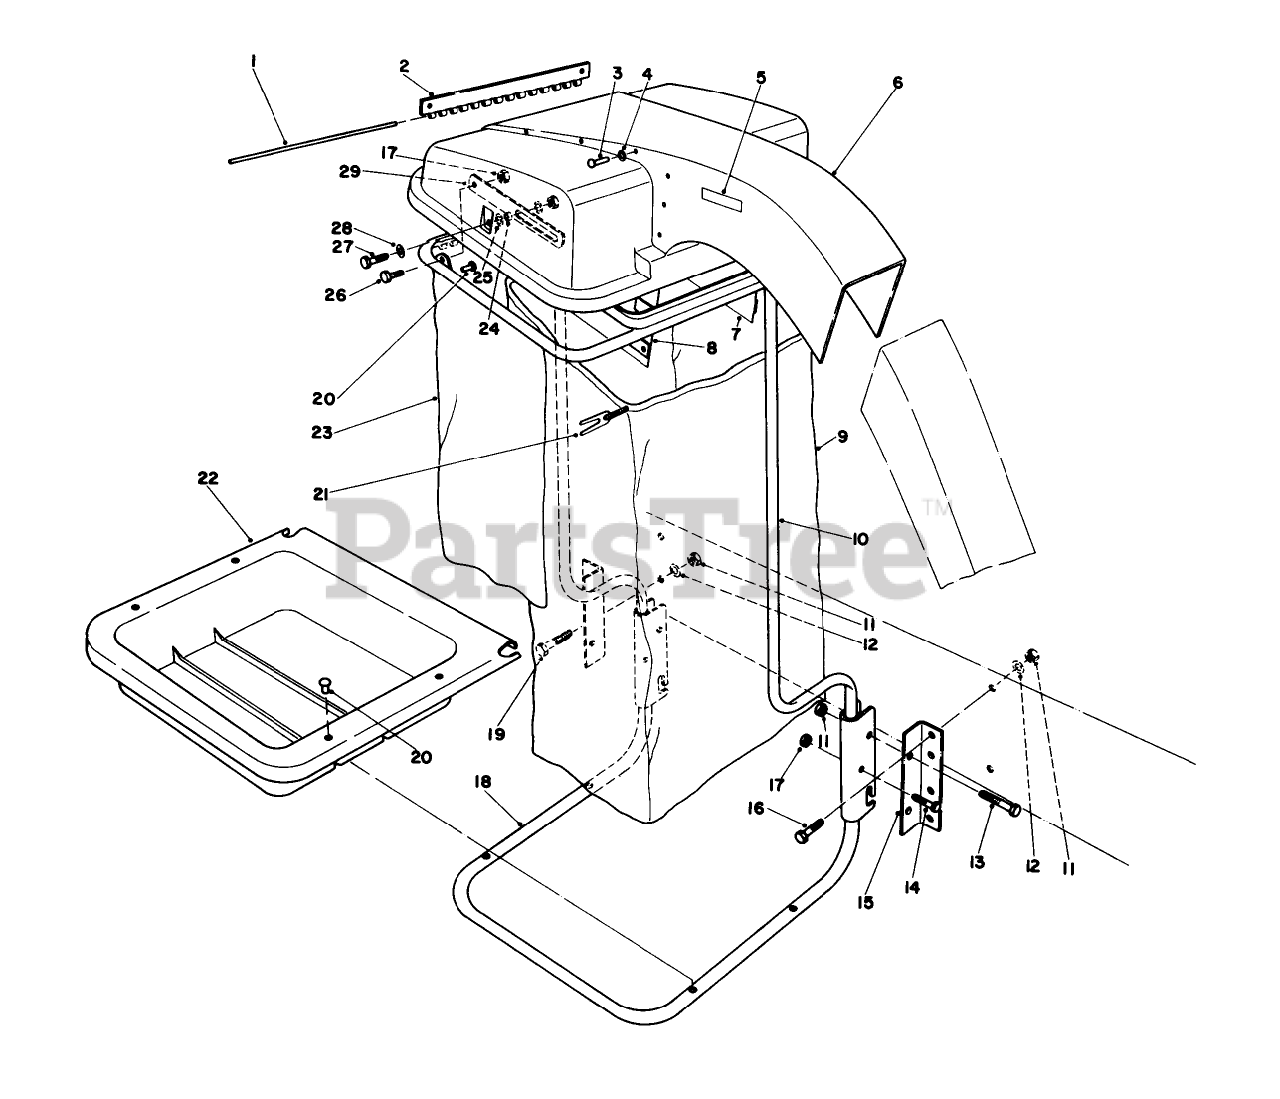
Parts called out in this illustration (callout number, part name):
1	HOOD HINGE PIN
2	Hinge-Half
3	POP RIVET 3/16X.375LG
4	WASHER-FLAT
5	Decal-Caution
6	Hood Assembly (Incl. Ref. #2-5, 7 & 8)
7	Screen Left Hand
8	Screen Right Hand
9	BAG-CLOTH, 32"
10	Support Tube Assy. Upper (Incl. Ref. #20 & 23)
11	NUT-LOCK, CONE
12	WASHER-FLAT
13	SCREW-HH
14	SCREW-HH
15	BRKT-FRAME B
16	SCREW-HH
17	NUT-LOCK, CONE
18	Support Tube Assy.-Lower (Incl. Ref. #20 & 22)
19	SCREW-HH
21	BAG CORD FASTENER
22	Tray Lower
23	Skirt-Bagging Frame
24	SPACER - PIVOT ARM
25	WASHER-FLAT
26	SCREW-HH
27	Screw
28	WASHER-FLAT
29	Stop-Hood
